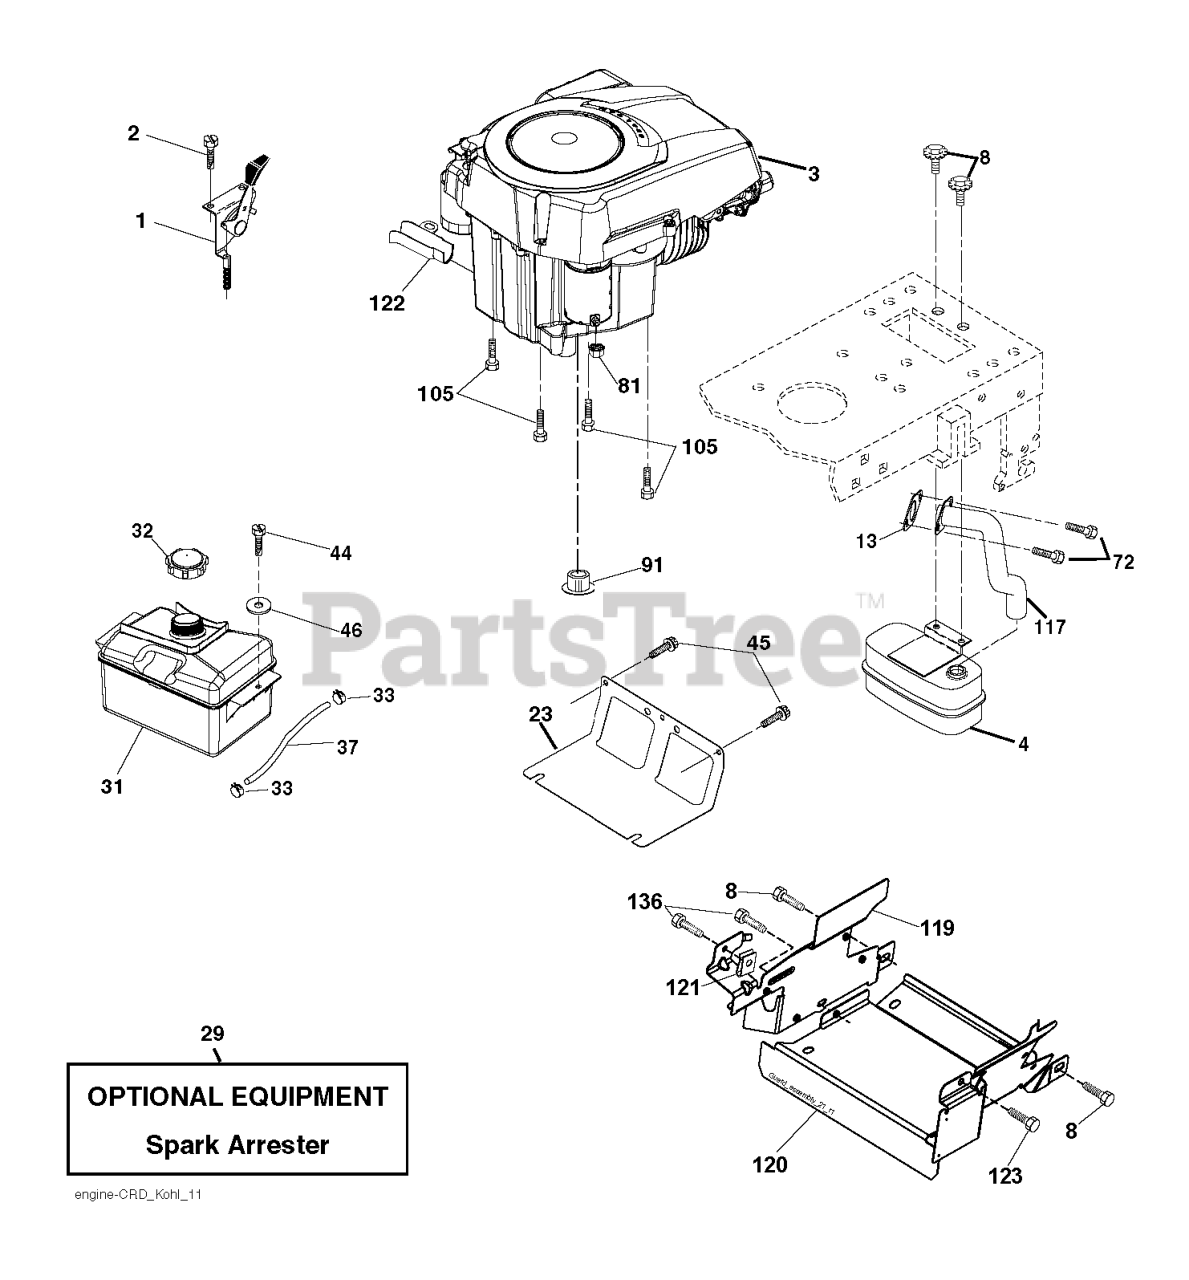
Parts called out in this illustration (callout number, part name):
1	CONTROL.TH/CK.C.
2	SCREW.#10 X 0.750.BOS
4	MUFFLER.SINGLE.CYL.KOHL/B&S
8	BOLT.5/16-18UNCX3/4 W/SEMS.BLK
13	GASKET.EXHAUST.KOHLER
23	SHIELD.BROWNING.DBR.GUARD
29	KIT.SPARK ARRESTOR 794945 B&S
31	RP TANK FUEL FRT 1.5 GAL
32	CAP ASM.FUEL.2.25"FR.
33	HOSE CLAMP
37	LINE.FUEL.20
44	SCREW HEXWSHR 1/4-20X3/4
45	SCREW, 3/8-16X3/4
46	WASHER
72	SCREW.SOCKET HD.5/16-1
81	NUT
91	BUSHING.1.375OD
105	SCREW 3/8-16X1
117	RP.TUBE.EXHAUST.KOHL.COURAGE
119	LENKRAD
120	GUARD 532199767
122	EXTENSION DRAIN OIL
123	SCREW, 5/16-18 X 1/2
136	SCREW.1/4-20X5/8
